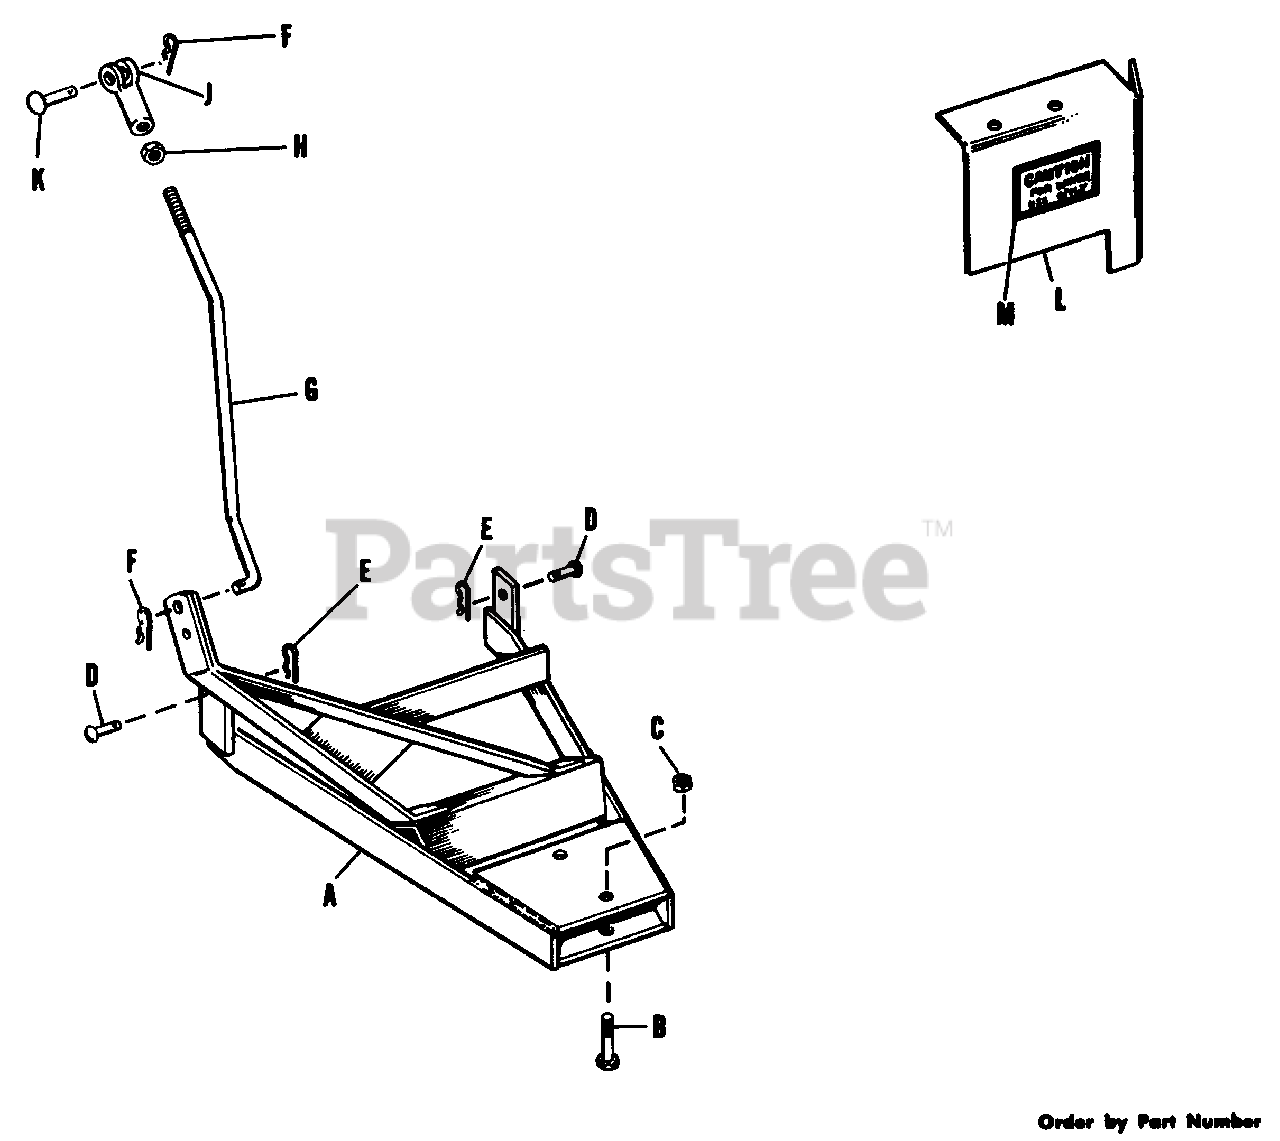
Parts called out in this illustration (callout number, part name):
A	Bar Assembly, Push
B	Capscrew, Hex Hd., 1/2" - 13 N. C. x 2-1/2" lg.
C	Nut, Hex, Full, Lock, 1/2" - 13 N. C.
D	Pin
E	Clip, Spring
F	Clip, Spring
G	Rod, Front Lift
H	Nut, Full, Hex, 1/4" - 20 N. F.
J	Yoke End, Adjusting
K	Pin, Yoke
L	Deflector, Hot Air
M	Decal, "Caution"
